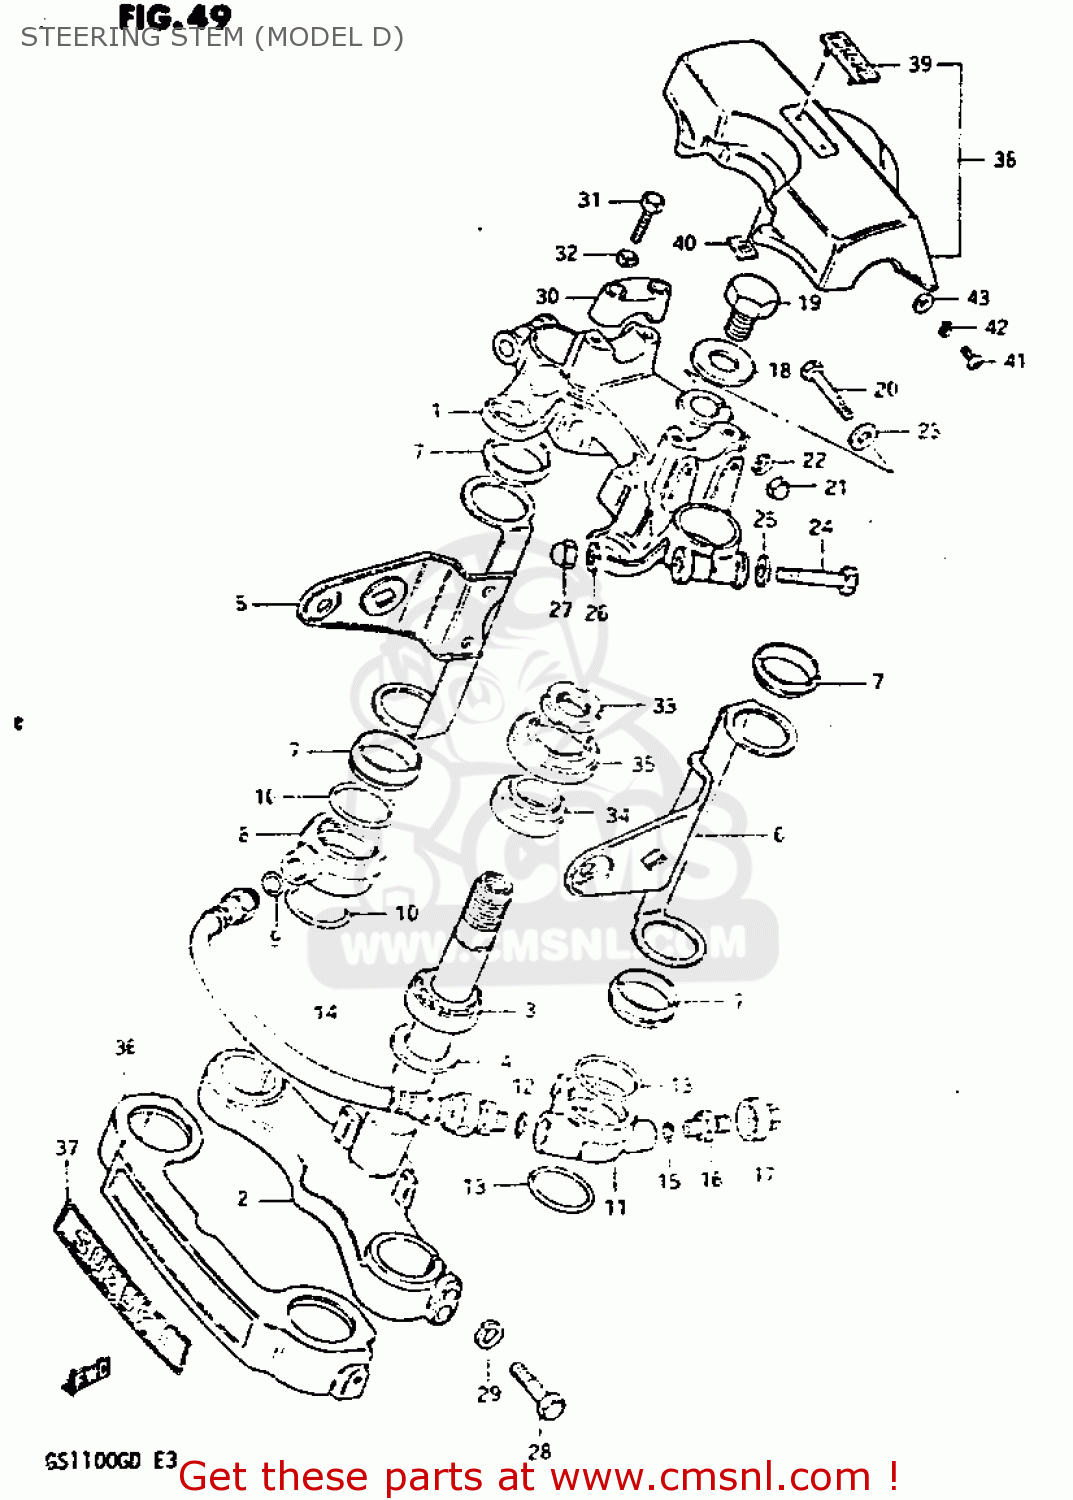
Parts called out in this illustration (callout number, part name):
1	HEAD,STEERING STEM
2	STEM,STEERING
3	BEARING(30X55X17)
4	WASHER,THRUST
5	BRACKET,HEADLAMP,RIGHT
6	BRACKET,HEADLAMP,LEFT
7	CUSHION,HEADLAMP BRACKET
8	JOINT,AIR,RIGHT
9	O-RING
10	O RING
11	JOINT,AIR,LEFT
12	O-RING
13	O RING
14	HOSE
15	O-RING
16	VALVE,FRONT FORK AIR
17	CAP,VALVE
18	WASHER,STEERING STEM
19	NUT,STEM HEAD
20	BOLT 8X50
21	NUT
22	LOCK WASHER
23	WASHER
24	BOLT 10X55
25	WASHER
26	WASHER,LOCK,10
27	NUT
28	BOLT
29	LOCK WASHER
30	HOLDER,HANDLE(BLACK)
31	BOLT
32	LOCK WASHER
33	NUT,STEERING STEM
34	TAPER,ROLLER BEARING
35	DUST SEAL,STEERING UPR
36	COVER,FRONT FORK
37	EMBLEM,FRONT FORK COVER
38	PAD,HANDLEBAR
39	EMBLEM,HANDLE COVER PAD
40	NUT
41	SCREW
42	LOCK WASHER
43	WASHER
